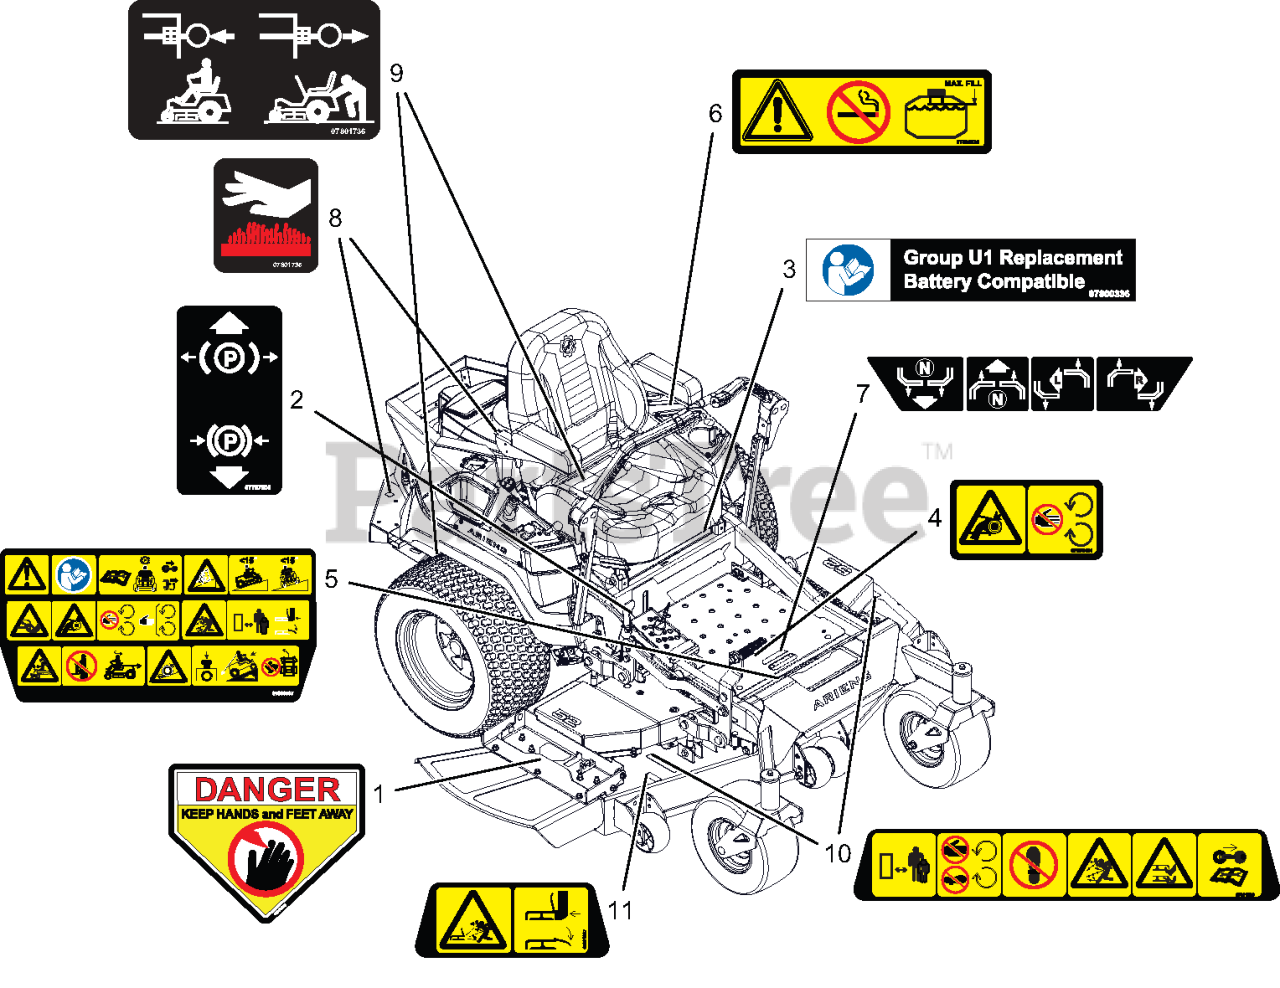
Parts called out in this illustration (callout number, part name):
1	DECAL, DANGER
2	DECAL, PARKING BRAKE LEVER
3	DECAL, U1 BATTERY REPLACEMENT
4	DECAL, SAFETY - GUARDING
5	DECAL, MAIN SAFETY
6	DECAL, FUEL WARNING
7	DECAL, INSTRUCTION - STEERING
8	DECAL- HOT SURFACE
9	DECAL- TRANSAXLE DISCONNECT
10	DECAL- SAFETY - MOWER DECK
11	DECAL- SAFETY - DECK GUARDING
